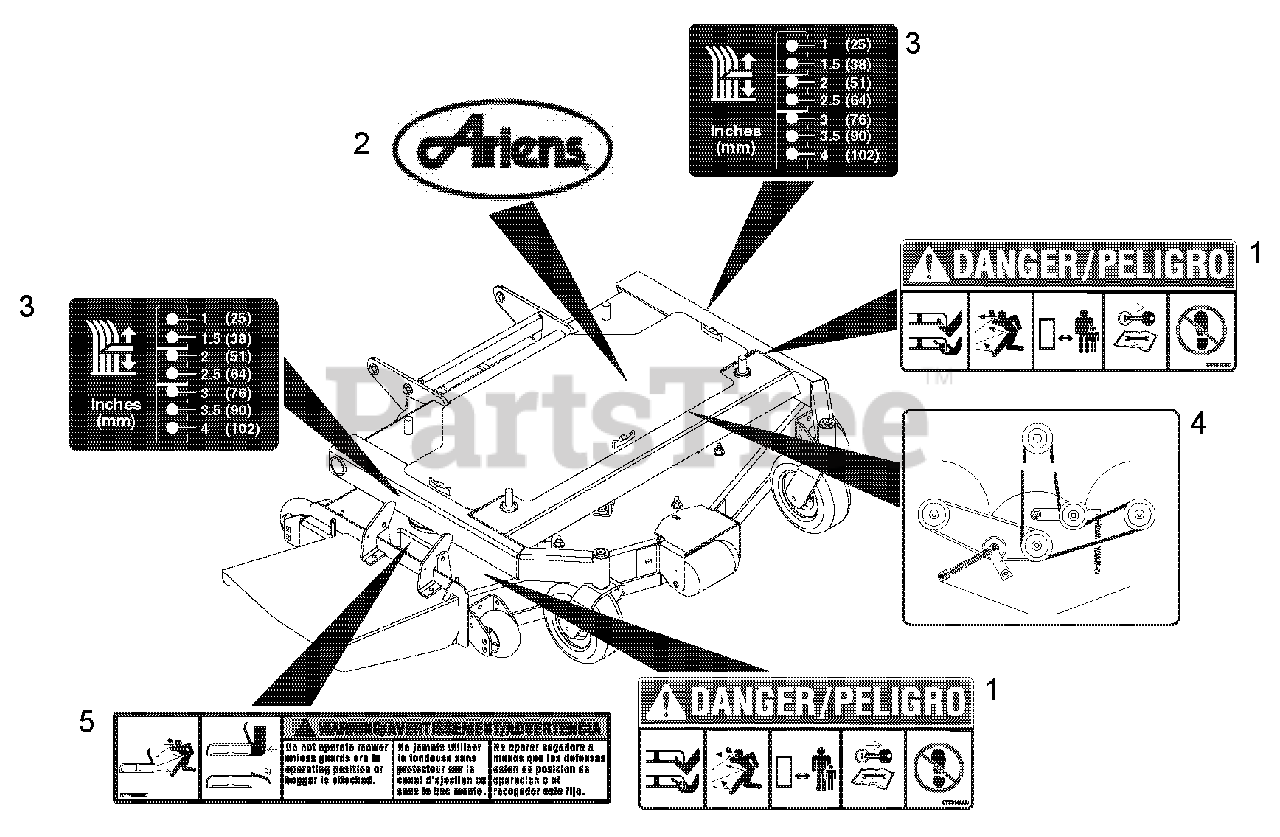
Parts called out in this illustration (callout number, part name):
1	DECAL, MOWER PAN DANGER
2	DECAL, ARIENS
3	DECAL-HEIGHT OF CUT - FLOATING
4	DECAL-BELT DIAGRAM-3 SPINDLE
5	DECAL, WARNING
